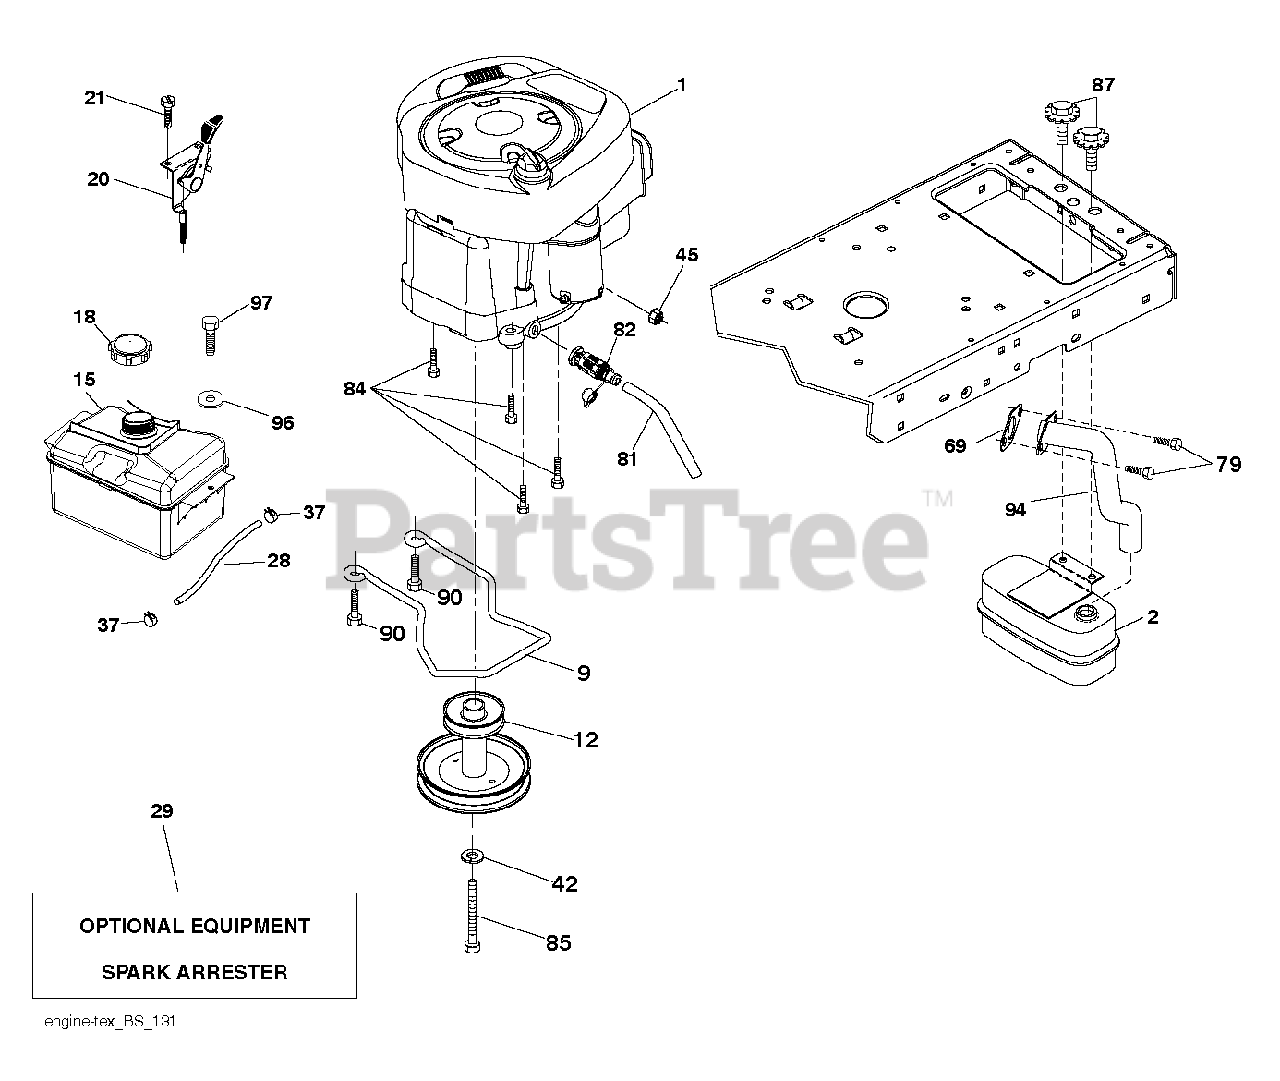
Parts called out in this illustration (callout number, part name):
2	MUFFLER.ASM.SNGL.XTNDED.DFLCTR
9	KEEPER.BELT.ENG.3.25"2BOLT.PNT
12	Engine Pulley
15	FUEL.TANK.ASM.1.5.GAL.NON-EPA
18	CAP ASM.FUEL.2.25"FR.
21	SCREW.#10 X 0.750.BOS (2 2)
28	LINE.FUEL.20
29	KIT.SPARK ARRESTOR(392390 B&S)
37	HOSE CLAMP
42	LOCKWASHER
45	NUT
79	SCREW.SOCKET HD.5/16-1
81	TUBE, DRAIN OIL ASM.
82	VALUE.OIL.DRAIN
84	SCREW.3/8-16
85	BOLT HEX 7/16-20X4-1/4"
87	BOLT, 5/16-18 X 1 3/4
90	SCREW 3/8-16X1
94	Exhaust Tube, B&S 28/31
97	SCREW HEXWSHR 1/4-20X3/4
